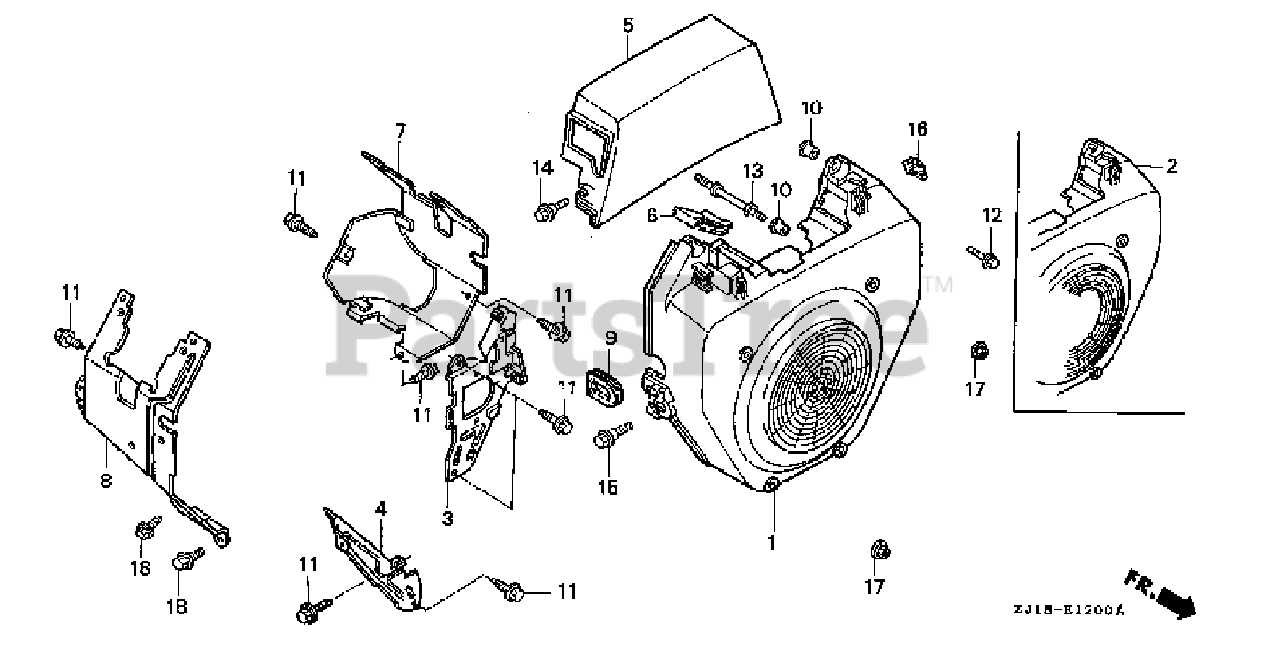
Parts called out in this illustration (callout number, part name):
2	COVER, FAN
3	PLATE, R. SIDE
4	PLATE, L. SIDE
5	HOOD, FAN COVER
6	PLUG, FAN COVER HOLE
7	SHROUD, R.
8	SHROUD, L.
9	GROMMET, WIRE
10	COLLAR B, TAILLIGHT
11	BOLT, FLANGE (6X12) (CT200)
12	BOLT, FLANGE (6X23)
13	BOLT, STUD (6X75)
14	BOLT, FLANGE (6X20)
15	BOLT, FLANGE (6MM) (BLACK)
16	NUT, SPRING (6MM)
17	NUT, FLANGE (6MM)
18	BOLT, FLANGE (6X8)
